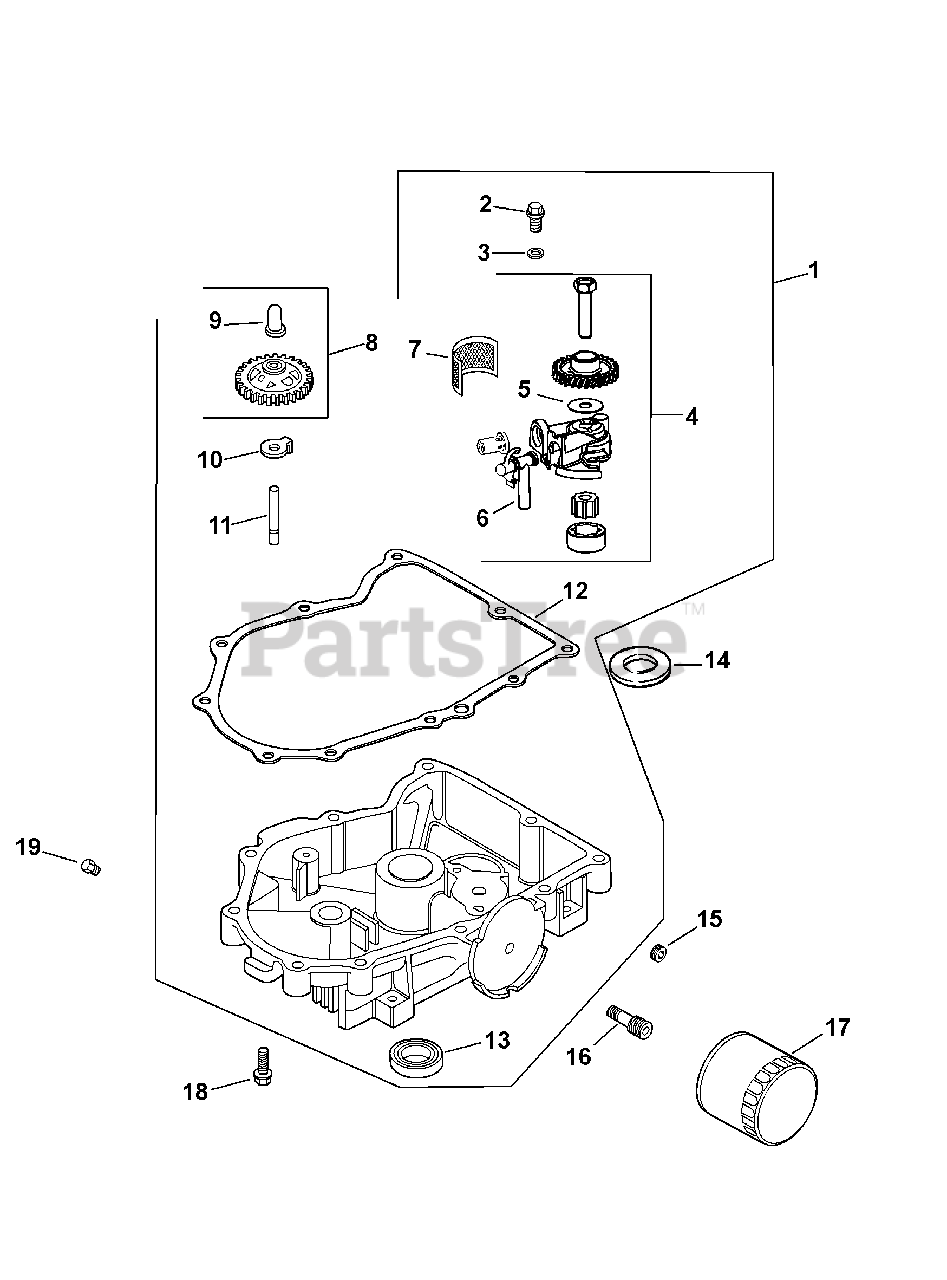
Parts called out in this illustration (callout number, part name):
1	Kit, Oil Pan Assembly (Inc. 2-13)
2	Screw, Flg Thd Frm M6X1.0X25
3	Washer, Flat 6MM
4	Kit, Oil Pump Assembly (Inc. 5, 6)
5	O-Ring, Oil Pick-Up
6	Tube, Oil Pick-Up
8	Kit, Governor Gear w/ Pin (Includes 9)
9	Pin, Governor Regulating
11	Shaft, Governor Gear
12	Kit, Oil Pan GSKT (Select-A-Seal)
15	Plug, Pipe CTSK 3/8"
16	Nipple, Oil Filter
18	Screw, Flg M8x1.25x45
19	Plug, Hd Pipe 3/8"
